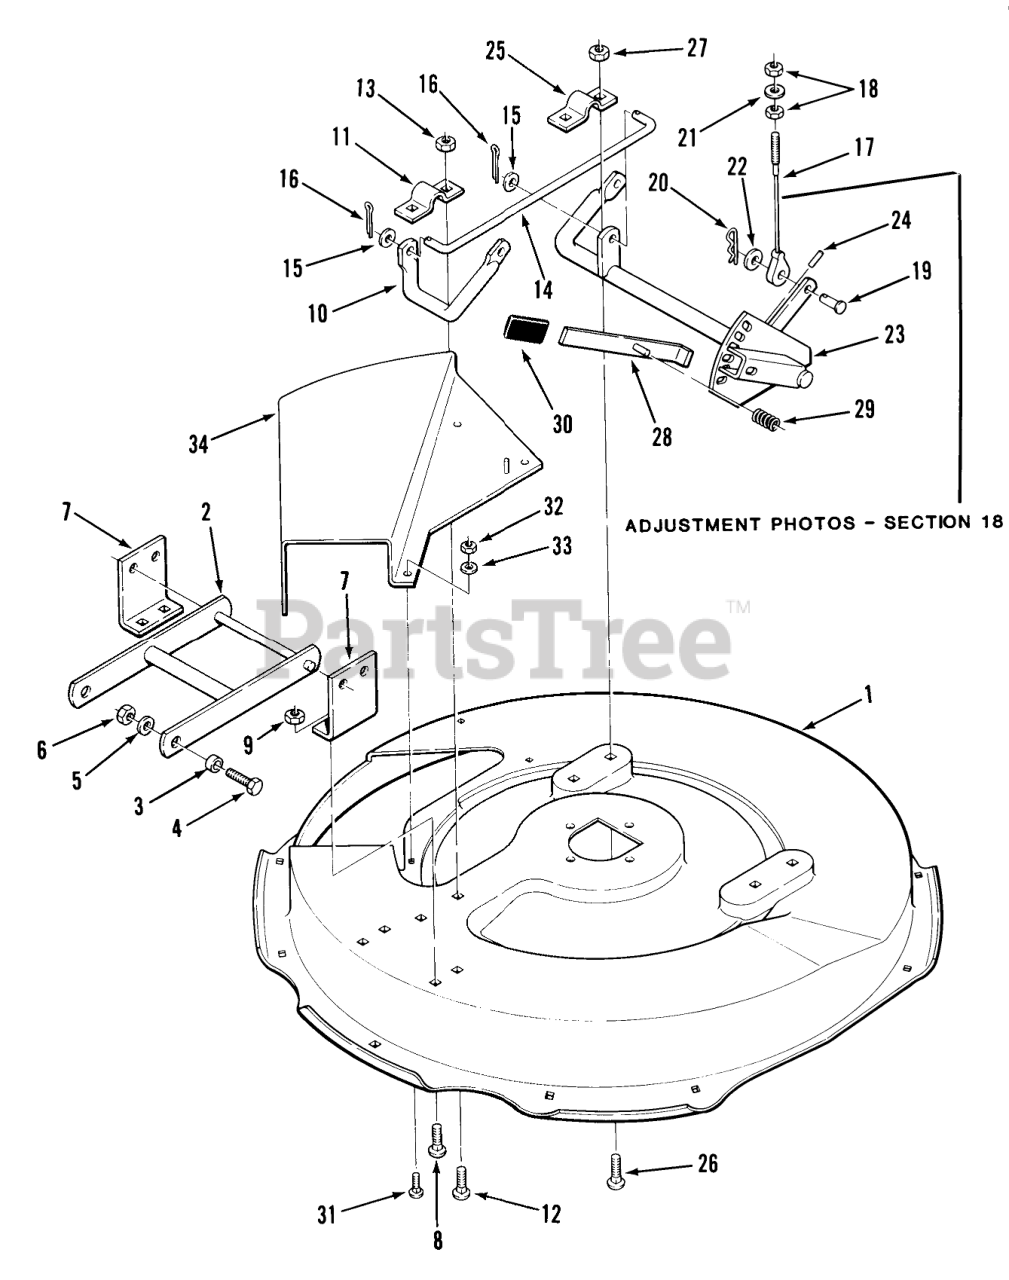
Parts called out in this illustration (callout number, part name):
1	Mower Deck Assy
2	ASSY MWR FRONT MO R
3	SPACER
4	Bolt
5	Washer
6	NUT
7	BRKT FRONT MOWER R
8	Bolt
9	NUT
10	ROD HEIGHT ADJ R
11	CLAMP
12	Bolt
13	NUT
14	Height Adjustment Rod
15	Washer
16	Cotter Pin
17	CABLE MOWER SUPPORT
18	Nut
19	CLEVIS PIN
20	Hairpin
21	WASHER 5/16 SAE
22	Washer
23	HEIGHT ADJ ASSY R
24	SPIROL PIN
25	CLAMP
26	Bolt
27	NUT
28	LEVER ASSY
29	SPRING-COMPRESSION
31	Bolt 1/4-20 X 5/8
32	Nut
34	Mower Deflector
